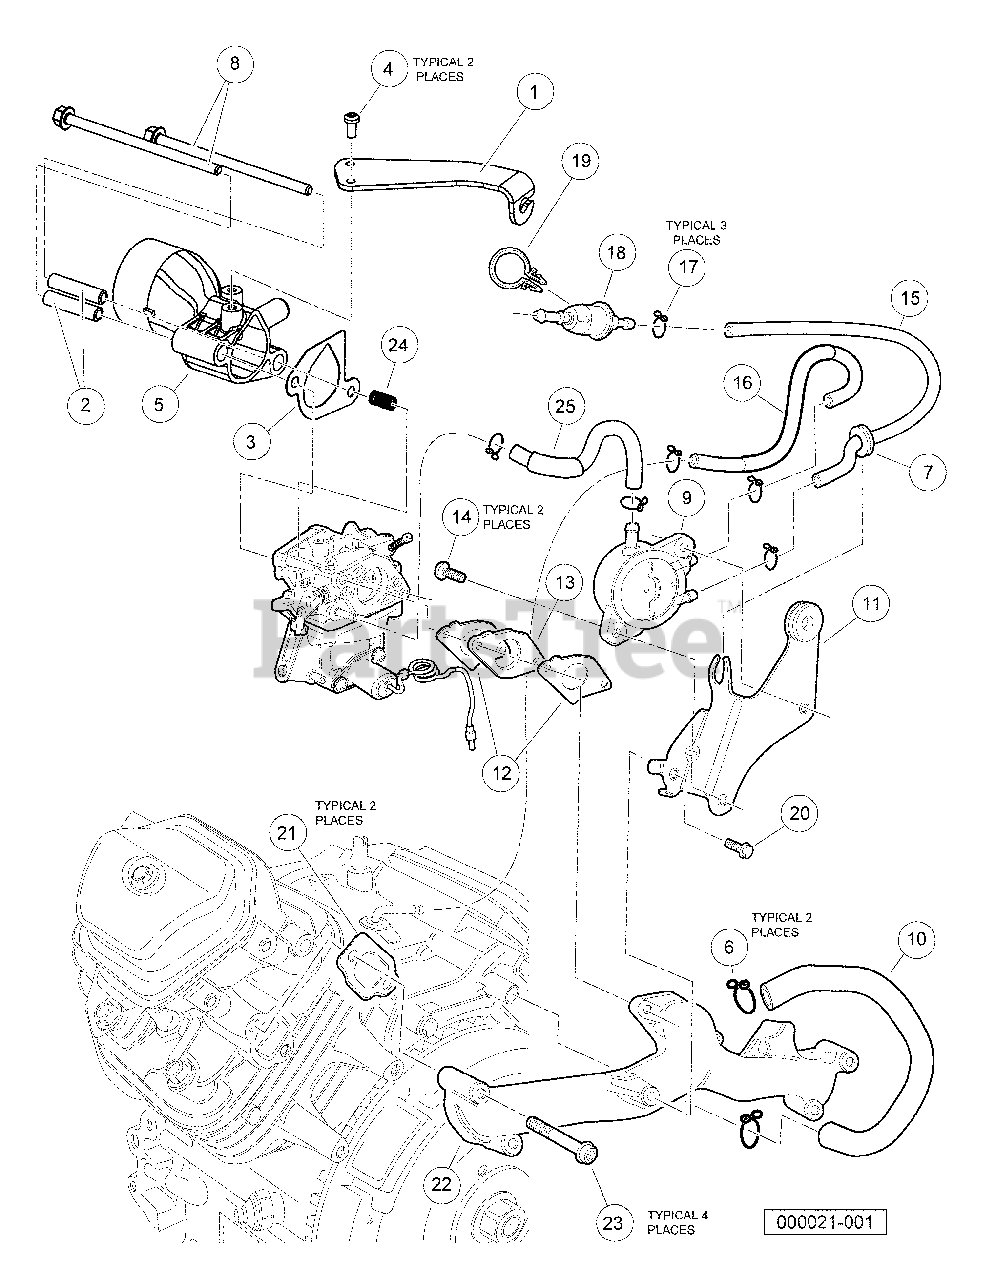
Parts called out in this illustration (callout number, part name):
1	Bracket, Choke Cable
2	Insert, Adapter, Carburetor
3	Gasket, Adapter, Carburetor
4	Screw Tapping, M5 X 0.8x10
5	Adapter, Intake Honda GX620
6	Clip, Breather Tube
7	Grommet, Reserve Tank
8	Bolt, Flange Head, M6 X 1 X 120
9	Pump Assy., Fuel, Sup
10	Tube, Breather
11	Stay, Fuel Pump
12	Gasket, Carburetor
13	Insulator, Carburetor
14	Srew-Washer, M6 X 16
15	Tube B, Fuel
16	Tube, Diaphragm
17	Clip, Tube, B10
18	Filter, Fuel
19	Clip, Wire Harness
20	Bolt, Flange Head, M6 X 11 X 4
21	Gasket, Intake Manifold
22	Manifold, Inlet
23	Bolt, Socket, M8 X 1.25 X 45
24	Spring, Continuity, Solenoid
25	Tube A, Fuel
